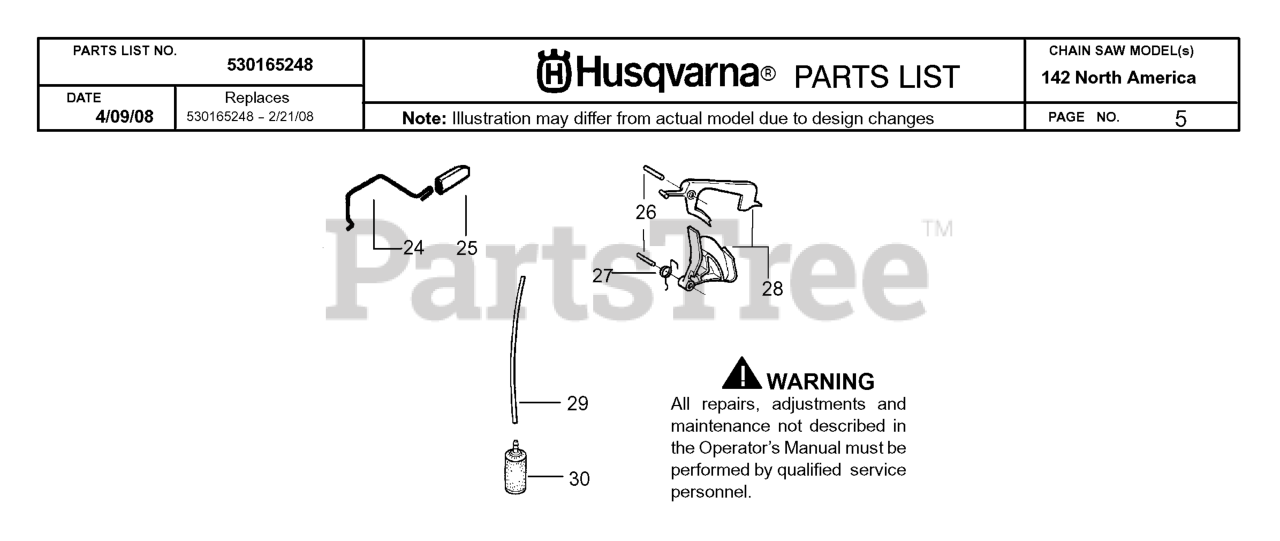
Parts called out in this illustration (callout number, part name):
24	THROTTLE SHAFT 36/41
25	THROTTLE ACTUATOR 36/41
26	PIN,TRIGGER 36/41
27	TRIGGER SPRING 36/41
28	THROTTLE TRIGGER-KIT
29	HOSE. FUEL
30	FUEL PICK-UP
